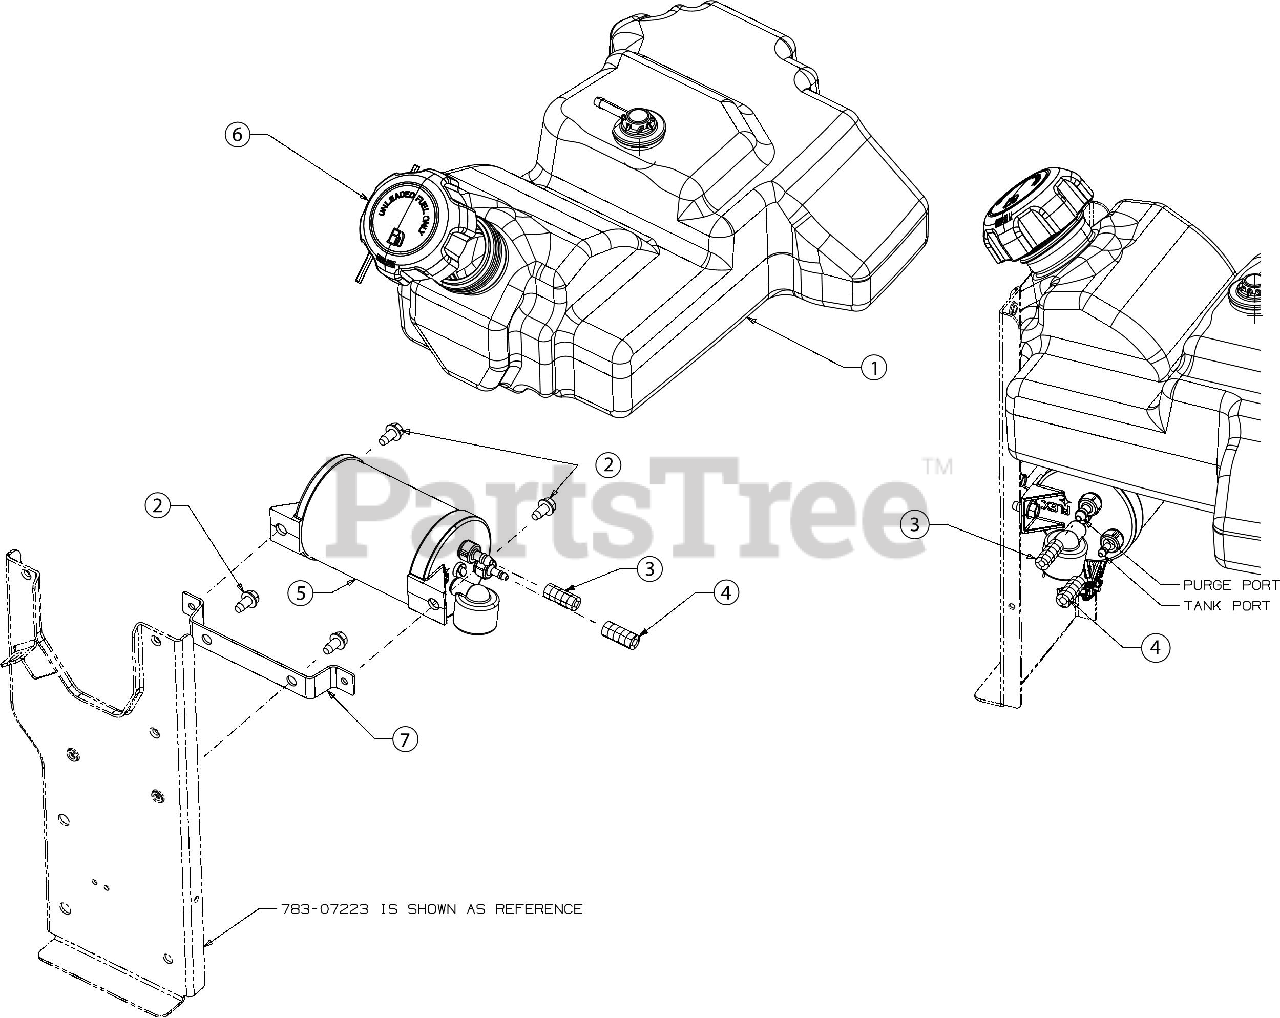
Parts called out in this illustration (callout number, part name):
1	FUEL TANK ASSEMBLY
2	SCREW 1/4-20 X.500
3	FUEL HOSE LOW PERMEATION
4	FUEL HOSE LOW PERMEATION
5	CARBON CANISTER
6	FUEL CAP W/TETHER
